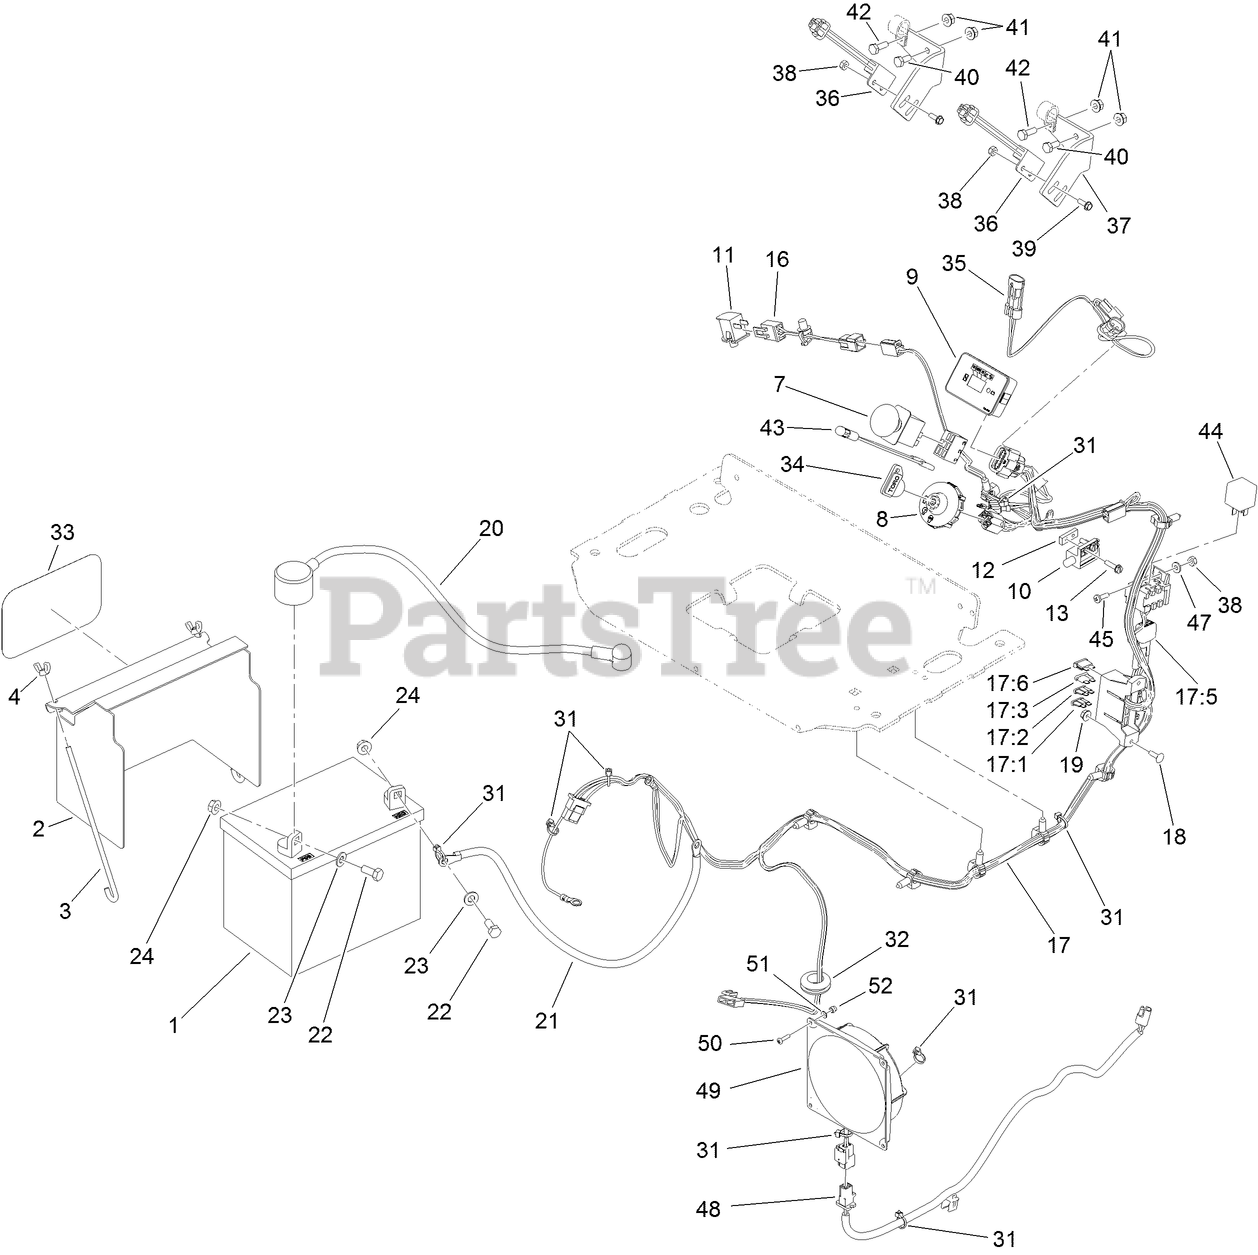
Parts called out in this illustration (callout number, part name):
1	BATTERY-DRY
2	COVER-BATTERY
3	BOLT-HOLDDOWN
4	WINGNUT
7	SWITCH-PTO, ON-ON-(ON)
8	SWITCH-IGNITION
9	MODULE-HOUR METER
10	SWITCH-CLOSED, NORMALLY
11	SWITCH-BAIL
12	PLATE-TAPPED
13	SCREW-HWH
16	HARNESS-WIRE, JUMPER (OPC)
17	Harness-Wire, EFI
17:1	FUSE-BLADE, 30 AMP
17:2	FUSE-BLADE, 25 AMP
17:3	FUSE-BLADE, 10 AMP
17:6	FUSE-BLADE, 15 AMP
18	BOLT-CARR
19	NUT-HF
20	CABLE-BATTERY, POSITIVE
21	CABLE-BATTERY, BLACK
22	SCREW-HH
23	WASHER-PLAIN
24	NUT-HHF, SMOOTH
31	TIE-CABLE
32	GROMMET
33	DECAL
34	KEY-IGNITION
35	HARNESS-WIRE, NEUTRAL SWITCH
36	SWITCH-PROXIMITY
37	BRACKET-MOUNT, SWITCH
38	NUT-LOCK, NI
40	SCREW-HH
41	NUT-HHF
42	SCREW-HH
43	INDICATOR-LED, RED
45	SCREW-PPH
47	WASHER-FLAT
48	HARNESS-WIRE, FAN
49	FAN-ELECTRIC
50	SCREW-PPH
51	WASHER-FLAT
52	NUT-LOCK
